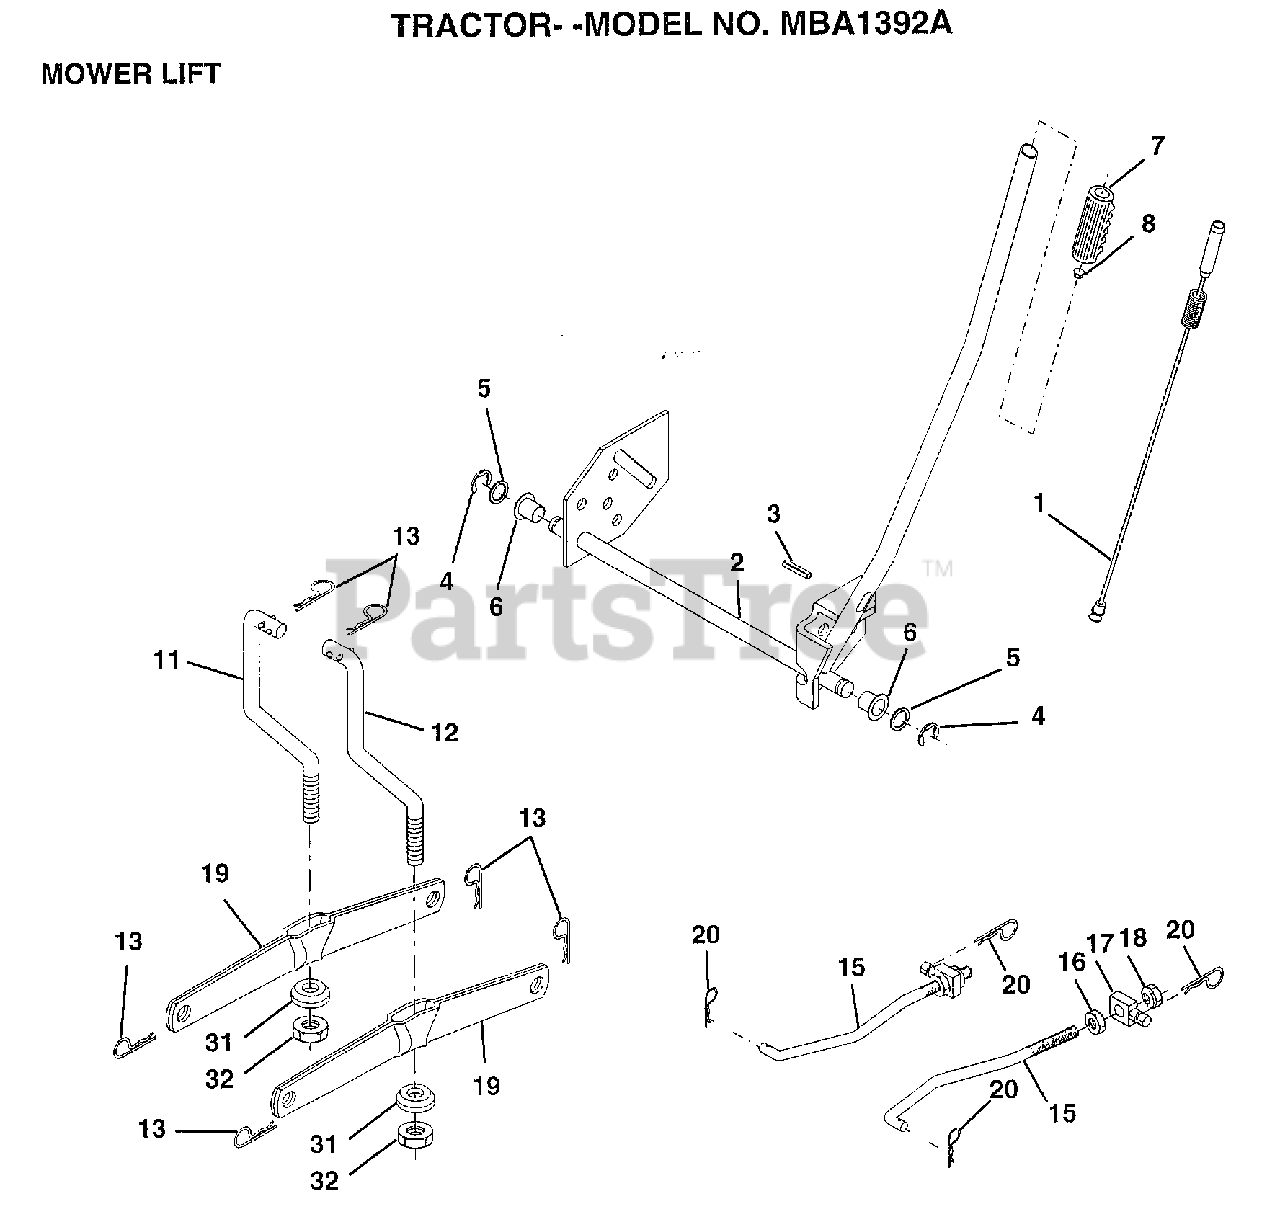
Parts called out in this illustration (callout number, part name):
1	WIRE ASM W.SPRING
2	"SHAFT ASM LIFT,RH"
3	PIN-GROOVE LT
5	WASHER
6	NYLON BEARING
7	GRIP
11	LINK.LIFT.LH.CRD
12	LINK.LIFT.RH.CRD
15	LINK.FRONT
16	NUT
17	TRUNION
18	NUT LTV
19	ARM SUSP REAR
20	RETAINER SPRING
31	BEARING PVT LH
32	NUT.CROWNLOCK.3/8
